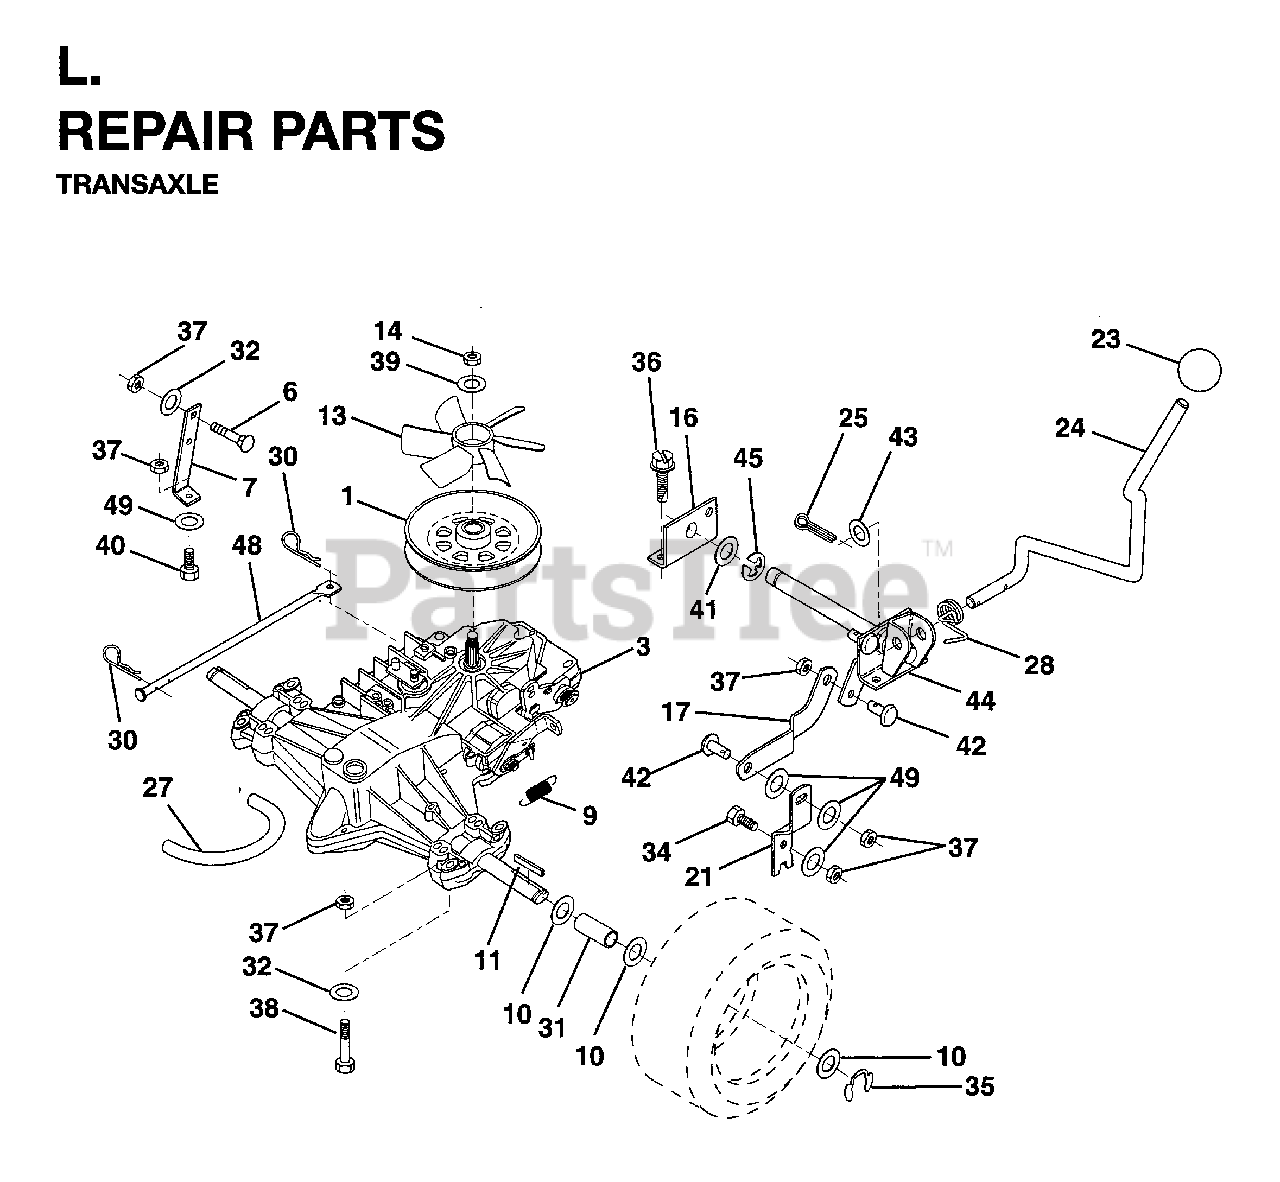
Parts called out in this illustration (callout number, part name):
3	TRANSAXLE HYDRO
6	BOLT
9	SPRING,BRAKE RETURN
11	SQUARE KEY
13	FAN.TRANSMISSION.HYDRO.6"
16	SUPPORT, SHIFT HANDLE
17	LINK, SHIFT
21	LEVER, SHIFT
23	KNOB.DELUXE.(PISTOL.GRIP).BLAC
24	ROD, SHIFTER
25	PIN COTTER
27	FUEL LINE
28	SPRING, TORSION
30	RETAINER M
31	SPACER SPLIT
32	WASHER - 15X7.3X1.6
35	E-RING LT
36	BOLT
37	NUT.71038.31-18.HEX.NYLOCK
40	HEX BOLT
44	SHAFT PIVOT ASMBLY
45	RETAINING RING LT
48	ACTUACTOR
49	WASHER - 15X7.3X1.6
